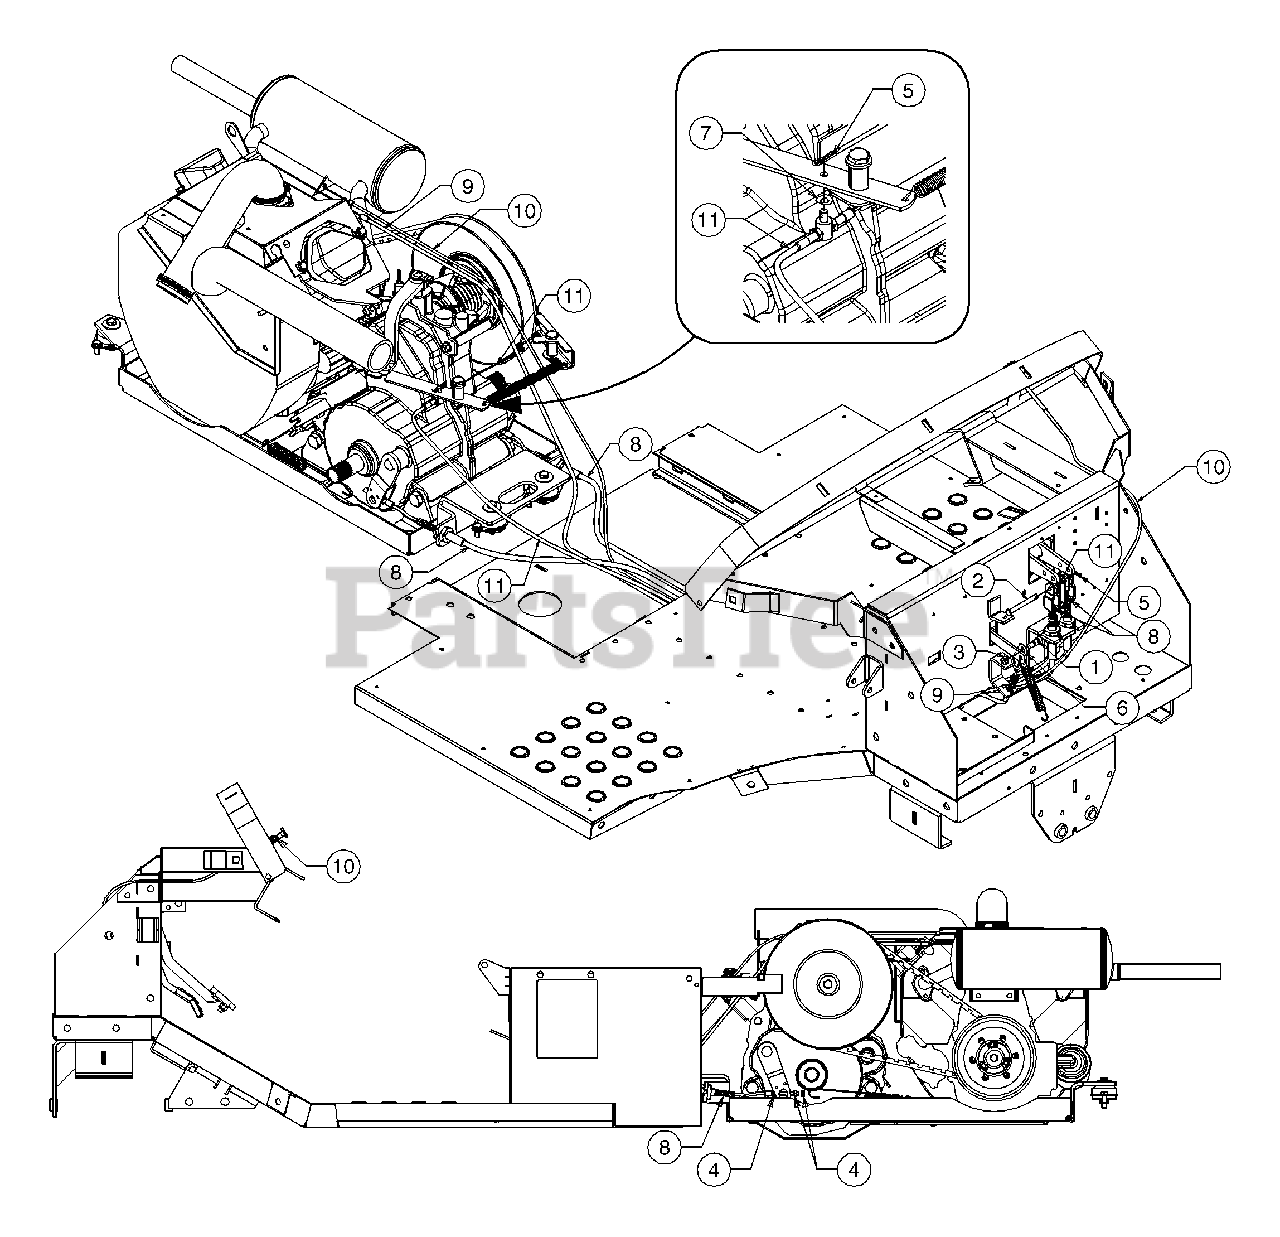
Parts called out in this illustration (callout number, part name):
1	Screw, Shoulder, .375 x .375
2	Pin, Clevis, 5/16 x 2.5
3	Nut, Hex Lock, 5/16-18
4	Nut, Jam, 5/16-24, Gr5
5	Pin, Cotter, .072 x 1.13
6	Washer, .349 x .879 x .063
7	Washer, Spring, .317 x .879 x .063
8	Cable, Control, Brake
9	Cable, Control, Throttle
10	Cable, Control, Choke
11	Cable, Control, Clutch Brake
